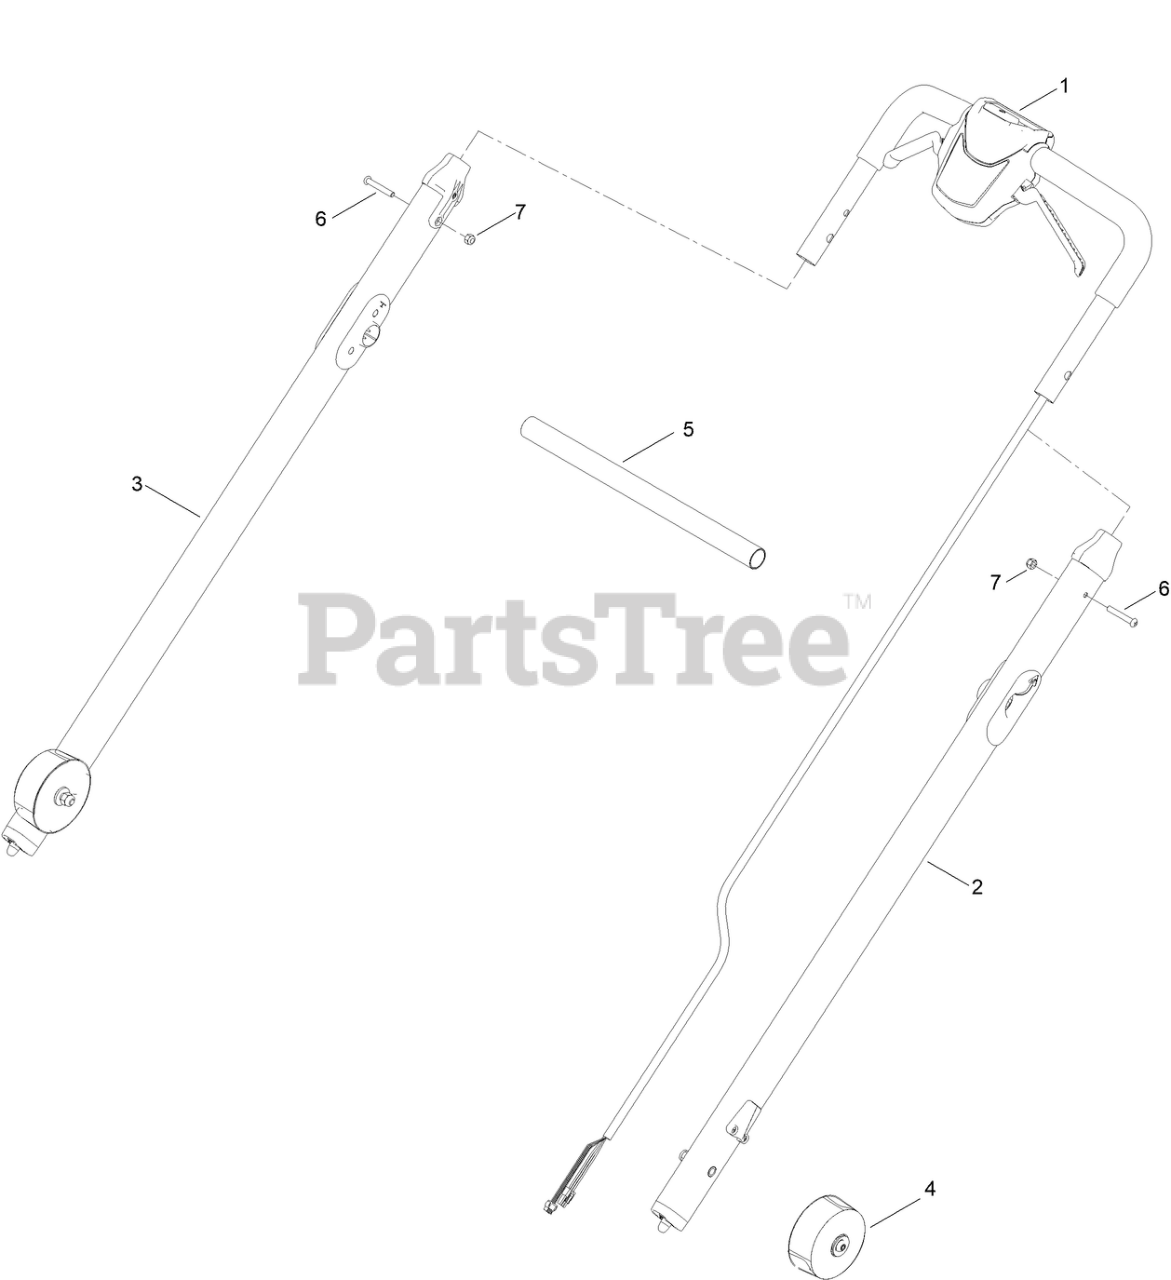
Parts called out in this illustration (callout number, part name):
1	HANDLEBAR CONTROL ASM, 36CM
2	HANDLEBAR ASM, LH
3	HANDLEBAR ASM, RH
4	HANDLEBAR END CAP
5	BRACE, HANDLEBAR RELEASE
6	BOLT, M6X40
7	NUT, M6, NYLOC
